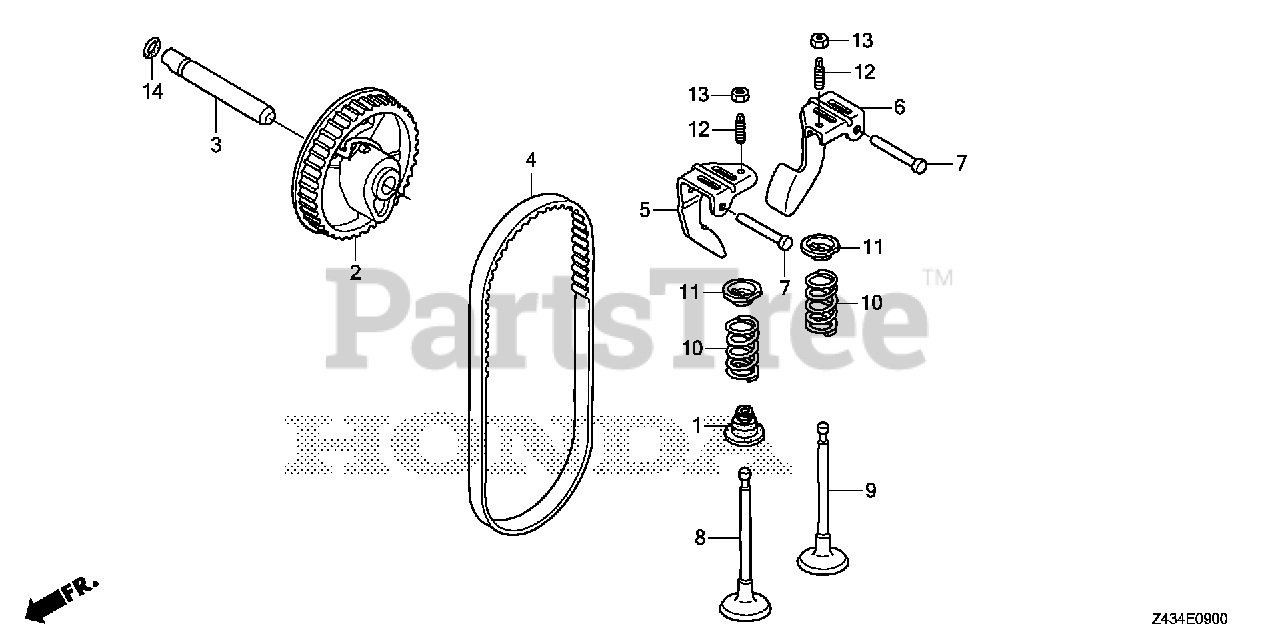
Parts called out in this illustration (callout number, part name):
1	SEAL, VALVE STEM
2	PULLEY, CAMSHAFT
3	SHAFT, CAM PULLEY
4	BELT, TIMING (84HU6 G-200)
5	ARM, IN. VALVE ROCKER
6	ARM, EX. VALVE ROCKER
7	SHAFT, ROCKER ARM
8	VALVE, IN.
9	VALVE, EX. (L8E)
9	VALVE, EX. (C8E)
10	SPRING, VALVE
11	RETAINER, VALVE SPRING
12	SCREW, TAPPET ADJUSTING
12	SCREW, TAPPET ADJ.
13	NUT, TAPPET ADJUSTING
13	NUT, TAPPET ADJ.
14	O-RING (6.8X1.9) (ARAI)
